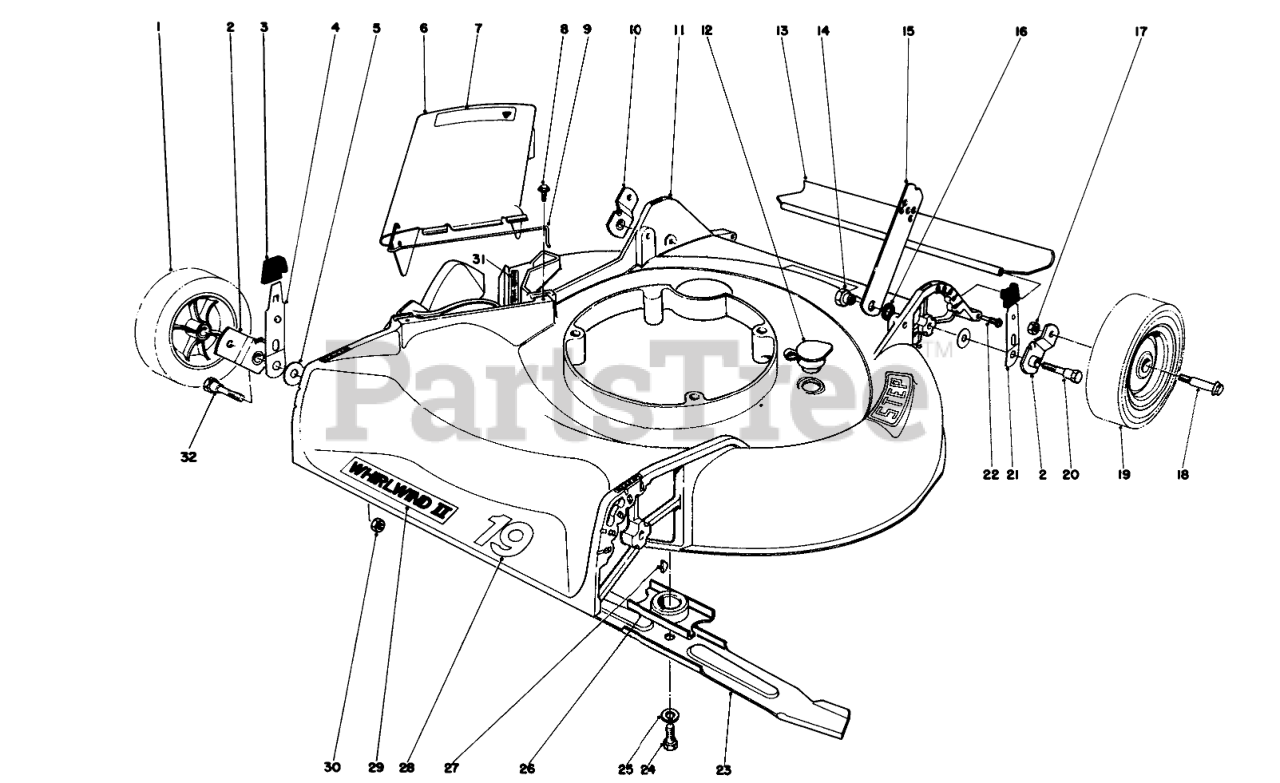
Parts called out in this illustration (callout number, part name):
1	Wheel Assembly
2	Pivot Arm
3	KNOB-ARM
4	SPRING ARM ASM
5	WASHER-PIVOT
6	Deflector Assembly (Incl.Ref. #7 & 9)
7	Caution Decal
8	SCREW
9	SPRING HINGE
10	Pivot Arm
11	Housing
12	WASHOUT PLUG
13	Rear Shield
14	HANDLE PIVOT NUT
15	Handle Latch
16	HANDLE LATCH SPACER
17	Nut
19	Wheel & Tire Assembly
20	PIVOT SCREW
21	SPRING ARM ASM
22	SAFTEY SHIELD SCREW
23	Blade
24	SPECIAL SCREW
25	WASHER-LOCK
26	Blade Retailer
27	KEY-WOODRUFF
28	Decal 19" (Model 16035)
29	Decal Whirlwind
30	Nut
31	Decal
32	PIVOT SCREW
